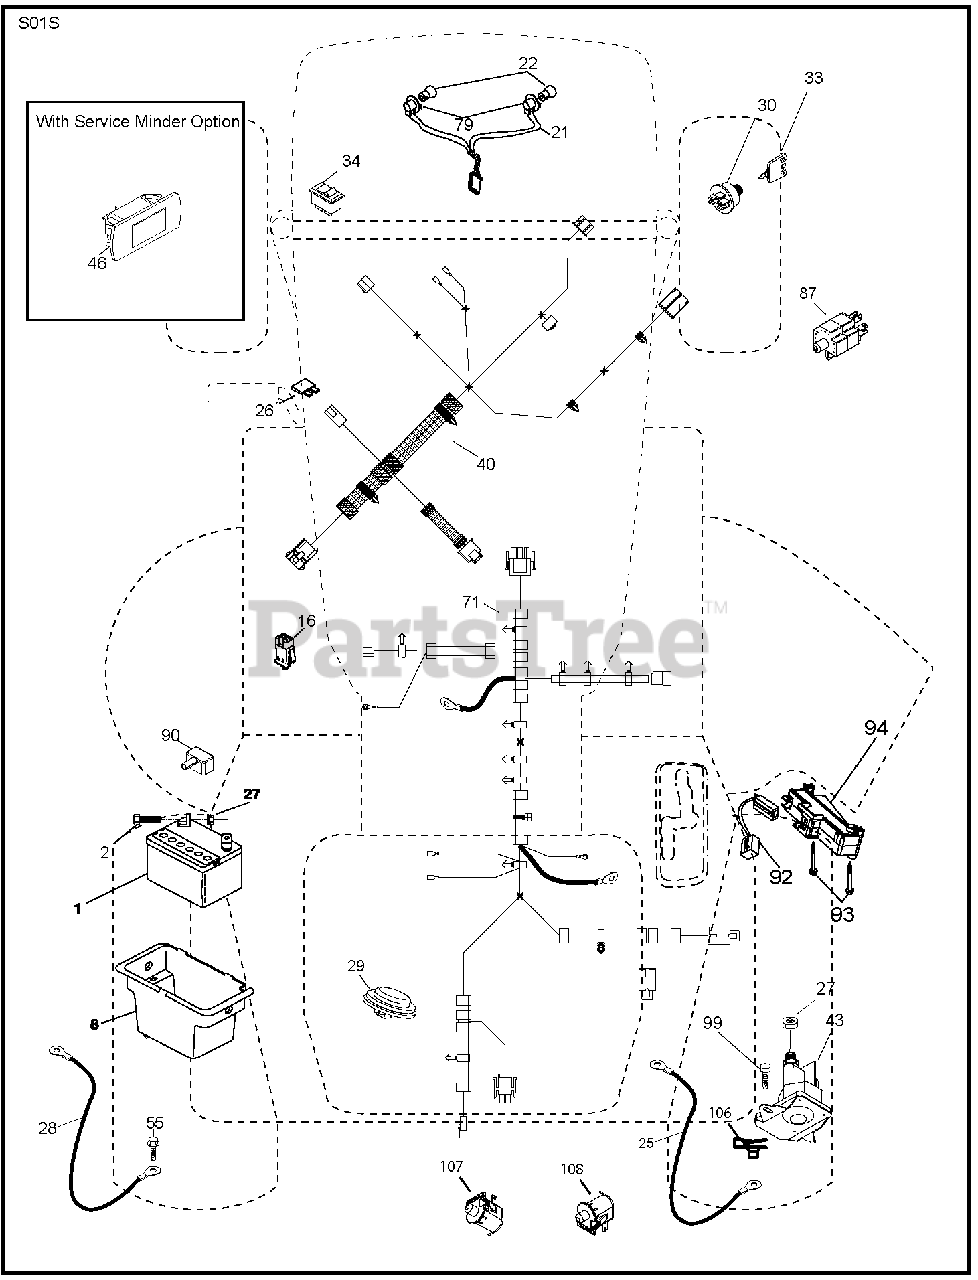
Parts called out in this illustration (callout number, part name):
1	REPL BY 532 12 38-99
2	BOLT.HEX.1/4.X.3/4.DICHROMATE
8	BOX.BATTERY.LT/SRD
16	SWITCH INTERLOOK PUSH-IN
21	HARNESS.LIGHT W/4152J BULBS
25	CABLE.BATTERY.20.RED.8 AWG
26	FUSE 20AMP
27	NUT
28	CABLE.GROUND.REAR.BATTERY.8G
29	SWITCH.SEAT.DELTA.OPC.
30	SWITCH.IGN.DELTA.W.LGH.ROS
33	KEY.CHAIN.BLISTER.PACK.GEN.INT
40	RP HARNESS.ELECTRICAL.DASH.SRD
43	SOLENOID.W/BRASS.PLUNGER
55	SCREW 5/16"
71	RP HARNESS.ELEC.CHASSIS.SRD
79	BULB HOLDER ASM.
87	RP SWITCH.RAILMOUNT.NO-NC-NC
90	COVER.TERMINAL.BATTERY
92	HARNESS.PIGTAIL.CONSLE
93	SCREW.PLASTITE
94	MODULE.REVERSE.ROS
99	SCREW HEXWSHR 1/4-20X3/4
106	1/4-20 U NUT
107	SWITCH.SNAPMOUNT.NO.#2
108	SWITCH.SNAPMOUNT.NC
